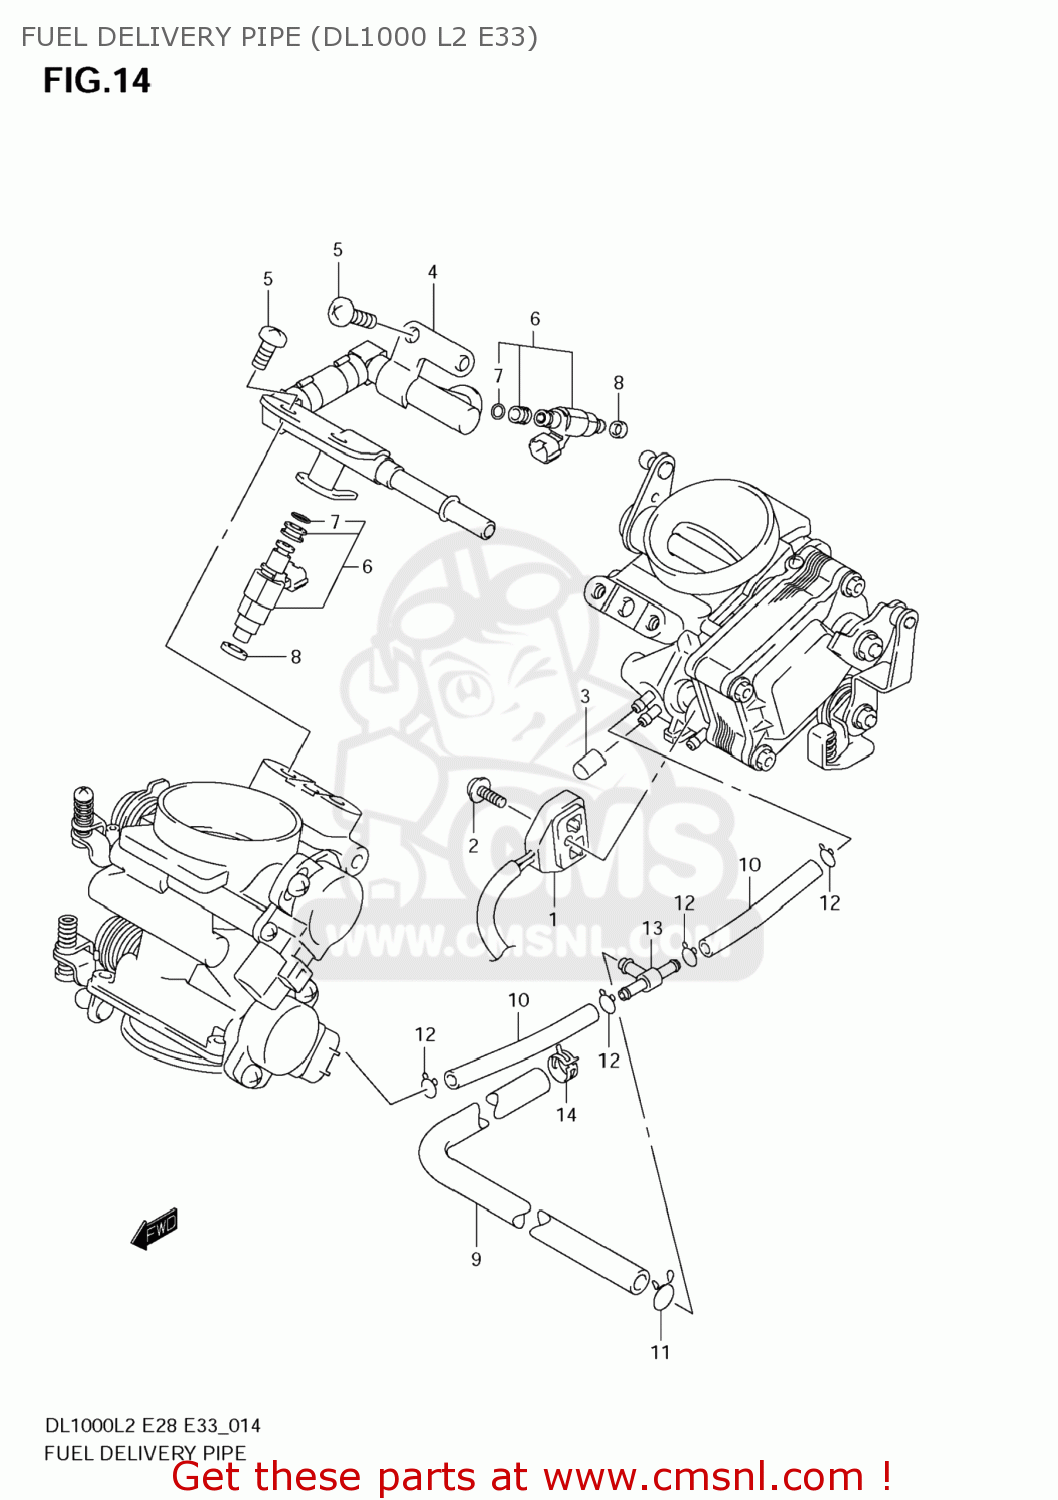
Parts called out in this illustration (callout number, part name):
1	HARNESS ASSY
2	SCREW
3	CAP
4	DELIVERY PIPE ASSY
5	SCREW
6	INJECTOR ASSY
7	O-RING
8	CUSHION,FUEL INJECTOR
9	HOSE
10	HOSE
11	CLIP
12	CLIP
13	NIPPLE
14	CLIP
